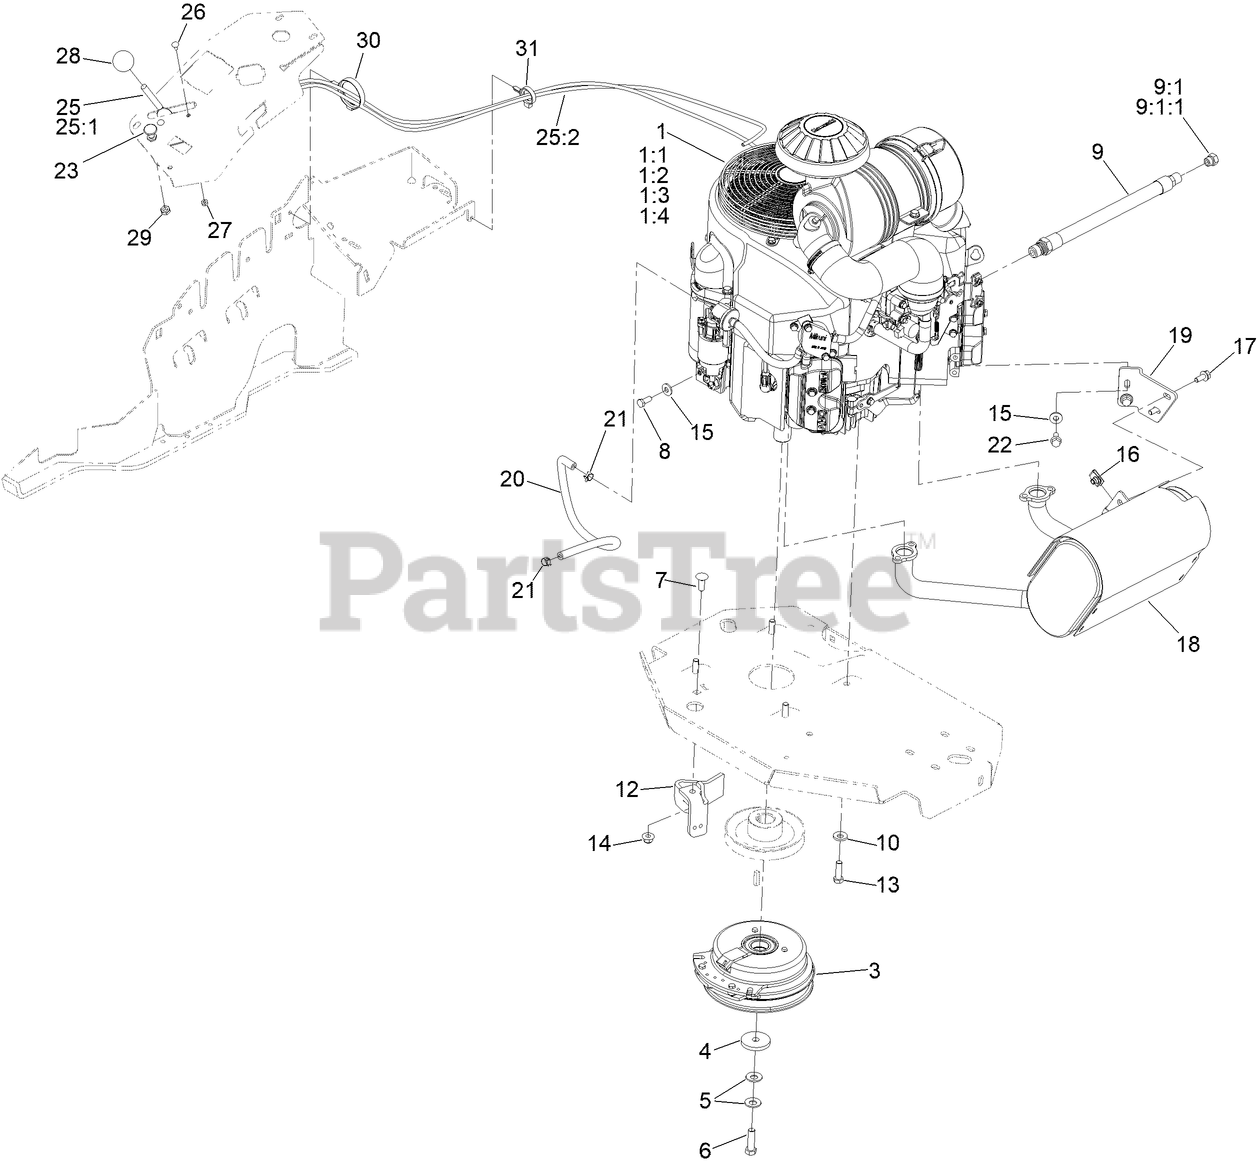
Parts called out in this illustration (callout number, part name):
1:1	KAWASAKI 49065-2078 ENGINE OIL FILTER
1:2	KAWASAKI 49019-0031 FUEL FILTER
1:3	KAWASAKI 11013-7039 SAFETY FILTER
1:4	KAWASAKI 11013-7038 AIR FILTER
3	CLUTCH KIT
4	WASHER-CLUTCH
5	WASHER-SPRING
6	SCREW-HH, W/LOCTITE
7	SCREW-CARR
8	SCREW-HH
9	ENGINE OIL DRAIN HOSE ASM
9:1	PLUG-HH
9:1:1	O-RING
10	WASHER-BELLEVILLE
12	CLUTCH-ANCHOR
13	SCREW-HH
14	NUT-HF, NI
15	WASHER-SPRING
16	NUT-U
17	SCREW-HHF
18	KIT, MUFFLER
19	BRACKET-MUFFLER
20	HOSE-FUEL
21	CLAMP-HOSE
22	SCREW-HHF
23	CONTROL-CHOKE
25	THROTTLE CONTROL ASM
25:1	LEVER-THROTTLE
26	BOLT-CARR
27	NUT-LOCK, NI
28	KNOB-BALL
29	NUT-HJ
30	CLAMP-HARNESS
31	CLAMP-HOSE
